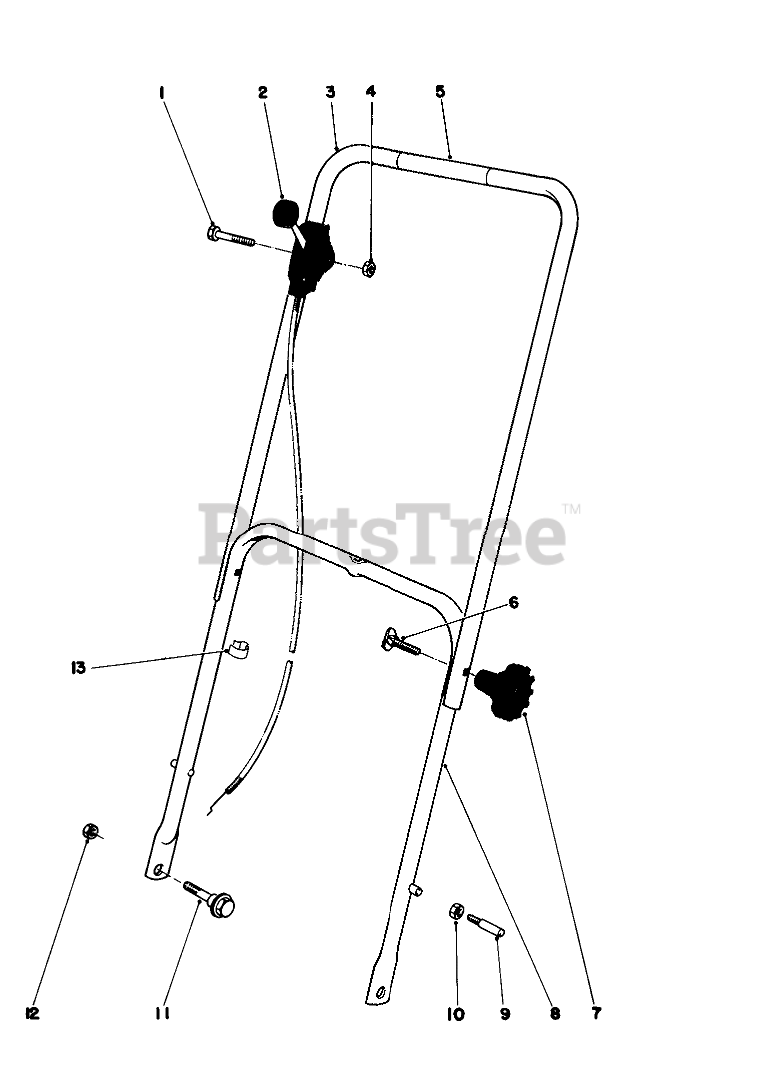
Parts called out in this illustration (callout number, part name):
1	SCREW-HH
2	Throttle Control
3	Upper Handle (Incl. Ref. #5)
4	NUT-LOCK
5	Danger-Decal
6	SCREW-HANDLE
8	19 LOWER HANDLE ASM
9	HANDLE PIN
10	Nut
11	SCREW-SHOULDER
12	Nut
